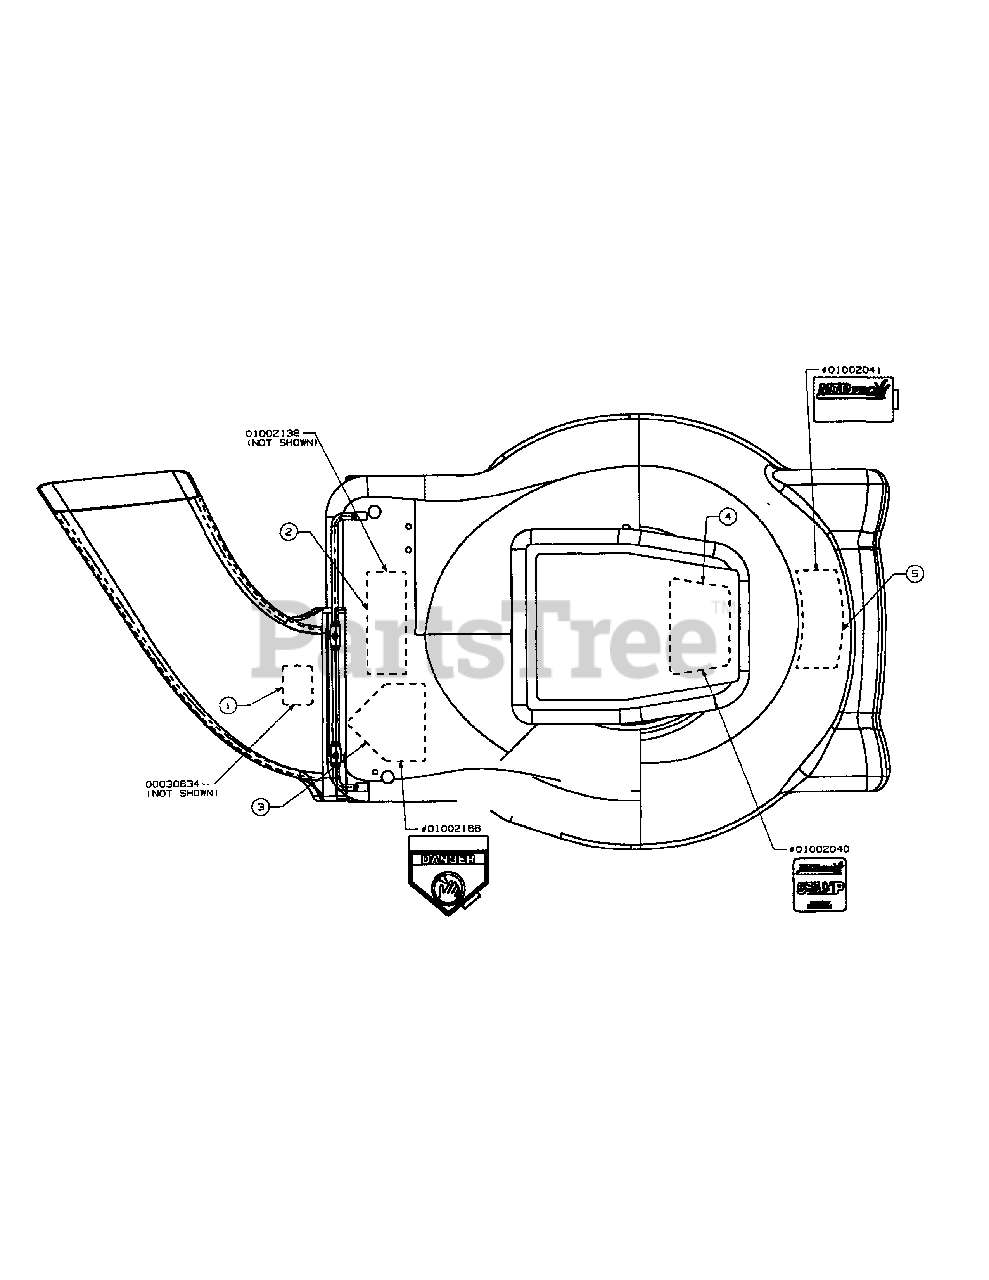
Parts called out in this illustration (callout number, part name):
1	LBL: DANGER, ROTATING BLADE
2	LBL: DANGER, AVOID SERIOUS
3	LBL: DANGER, HANDS & FEET
4	LBL: POWERED BY KAWASAKI
5	LBL: 5.5HP/21"
